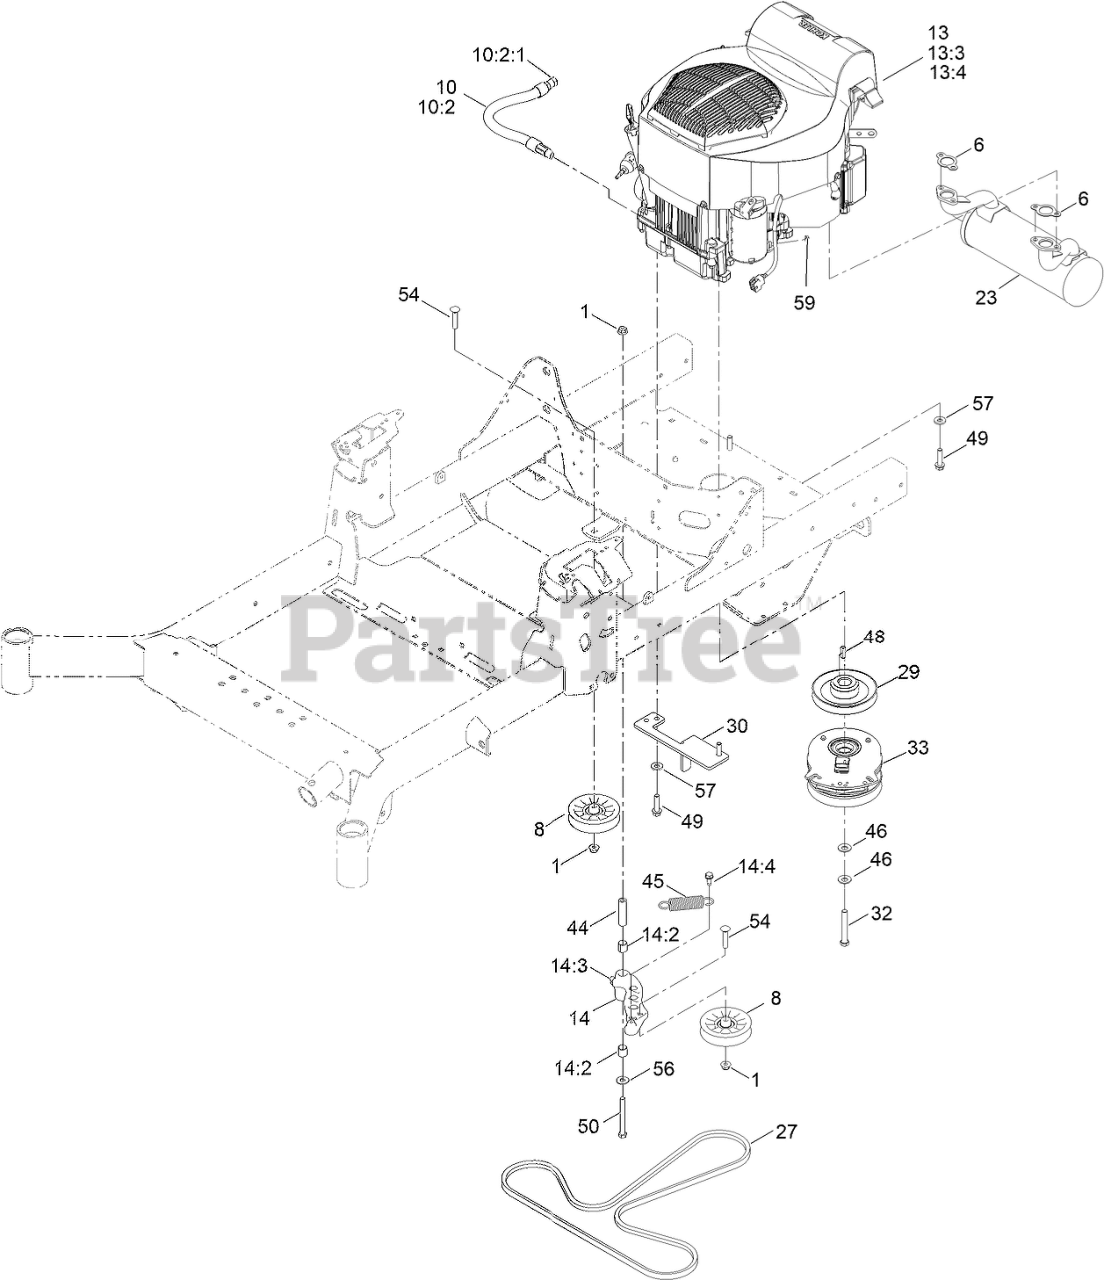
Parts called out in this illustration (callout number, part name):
1	NUT-HF, NI
8	PULLEY-FLAT IDLER
10	OIL DRAIN HOSE ASM
10:2	PLUG-HH
10:2:1	O-RING
13:3	GASKET-EXHAUST
13:4	PLUG-PIPE, SQH
14	IDLER ARM ASM
14:2	SLEEVE-BEARING
14:3	FITTING-GREASE, 90 DEG
14:4	SCREW-THD ROLL, HWH
23	MUFFLER-KOHLER AES
27	BELT-V
29	SHEAVE-ENGINE
30	ANCHOR-CLUTCH
32	SCREW-HH W/LOCTITE
33	CLUTCH-PTO
44	BUSHING-PIVOT, IDLER
45	SPRING-EXTENSION
46	WASHER-SPRING
49	SCREW-HWH
50	SCREW-HH
54	SCREW-CARR
56	WASHER-FLAT
57	WASHER-BELLEVILLE
59	NUT-HF
